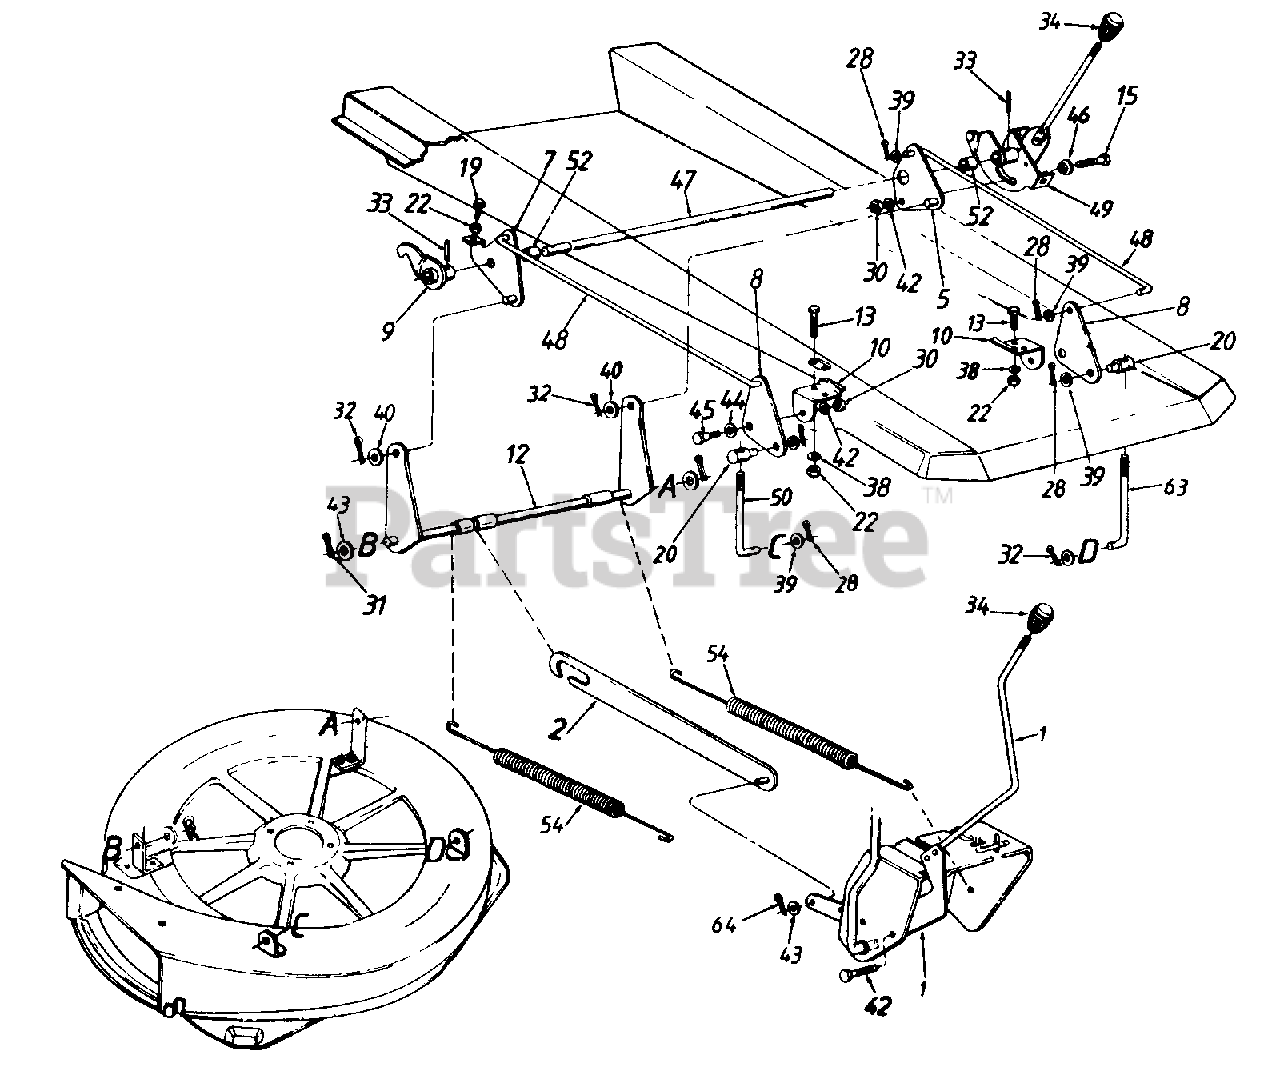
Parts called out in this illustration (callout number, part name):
7	Deck Lift Brkt. Ass'y.
8	Deck Lift Bracket
9	Deck Lift Float Brkt Ass'y.
10	Deck Lift Pivot Brkt.
15	Hex Bolt 3/8-16 x 1" Lg.
19	Hex Wash.-Tap Scr. 5/16-18 x 1.25" Lg.
20	Ferrule
22	Hex Nut 5/16-18 Thd.
28	Cotter Pin 3/32" Dia.
30	Hex Nut 3/8-16 Thd.
31	Internal Cot. Pin 1/2" Dia.
32	Int. Cot. Pins 3/8" Dia.
33	Spring Pin Spir. 1/4" Dia.
34	Knob
38	L-Wash 5/16" I.D.
39	Fl-Wash. .385 I.D. x .62
40	Fl-Wash. .635 I.D. x 1.12
42	L-Wash. 3/8" I.D.
43	Fl-Wash. .385 I.D. x .87 O.D.
44	Spring Washer .530 I.D.
45	Shld. Bolt .500" Dia. x .215"
46	Shld. Spacer .625" I.D.
47	Rear Hgt. Adj. Shaft
50	J-Bolt 3/8-24 x 5.25" Lg.
52	Spacer .885 I.D.
54	Ext. Spring 13.25" Lg.
63	J-Bolt 3/8-24 x 5.4" Lg.
64	Cotter Pin 1/8" Dia.
